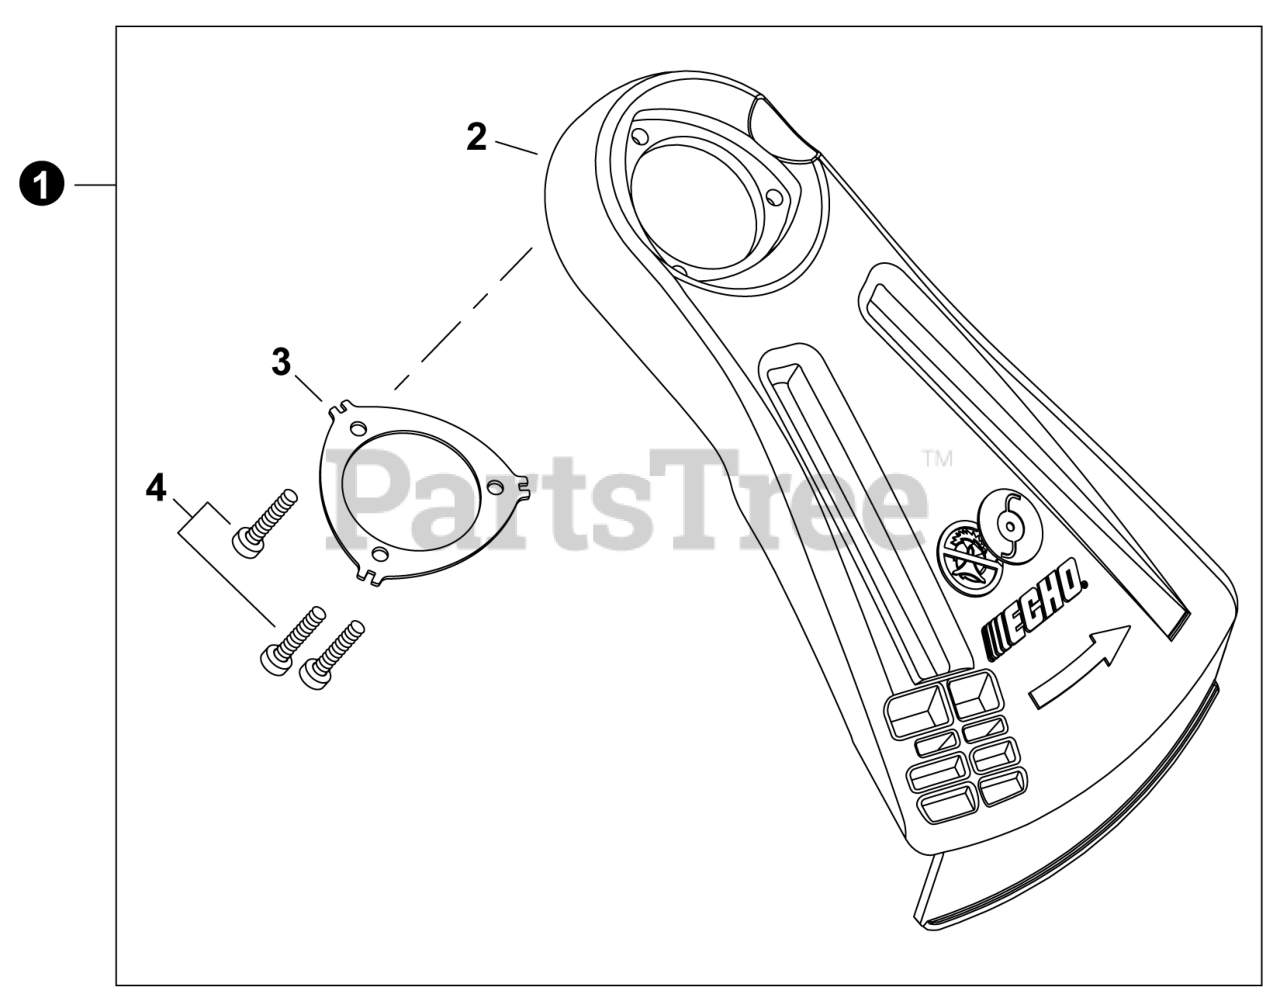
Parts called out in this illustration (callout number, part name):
1	SHIELD KIT, DEBRIS
2	SHIELD, DEBRIS
3	PLATE, SHIELD
4	BOLT, TORX 5x16
